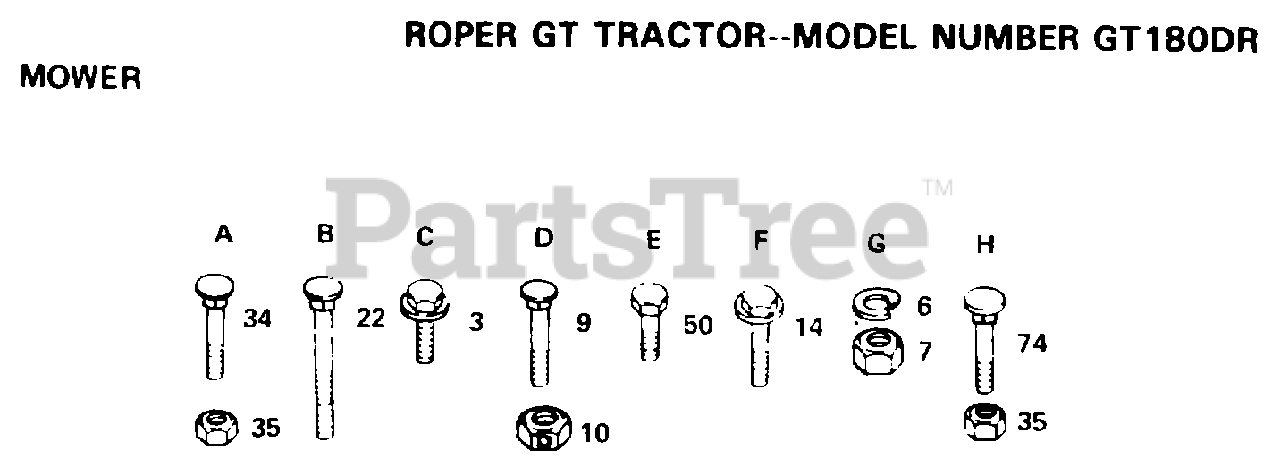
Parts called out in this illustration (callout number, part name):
3	SCREW LT
6	LOCKWASHER
7	NUT.HEX.5/16-18
9	BOLT
14	SCREW
22	BOLT
34	BOLT
50	BOLT
74	BOLT
